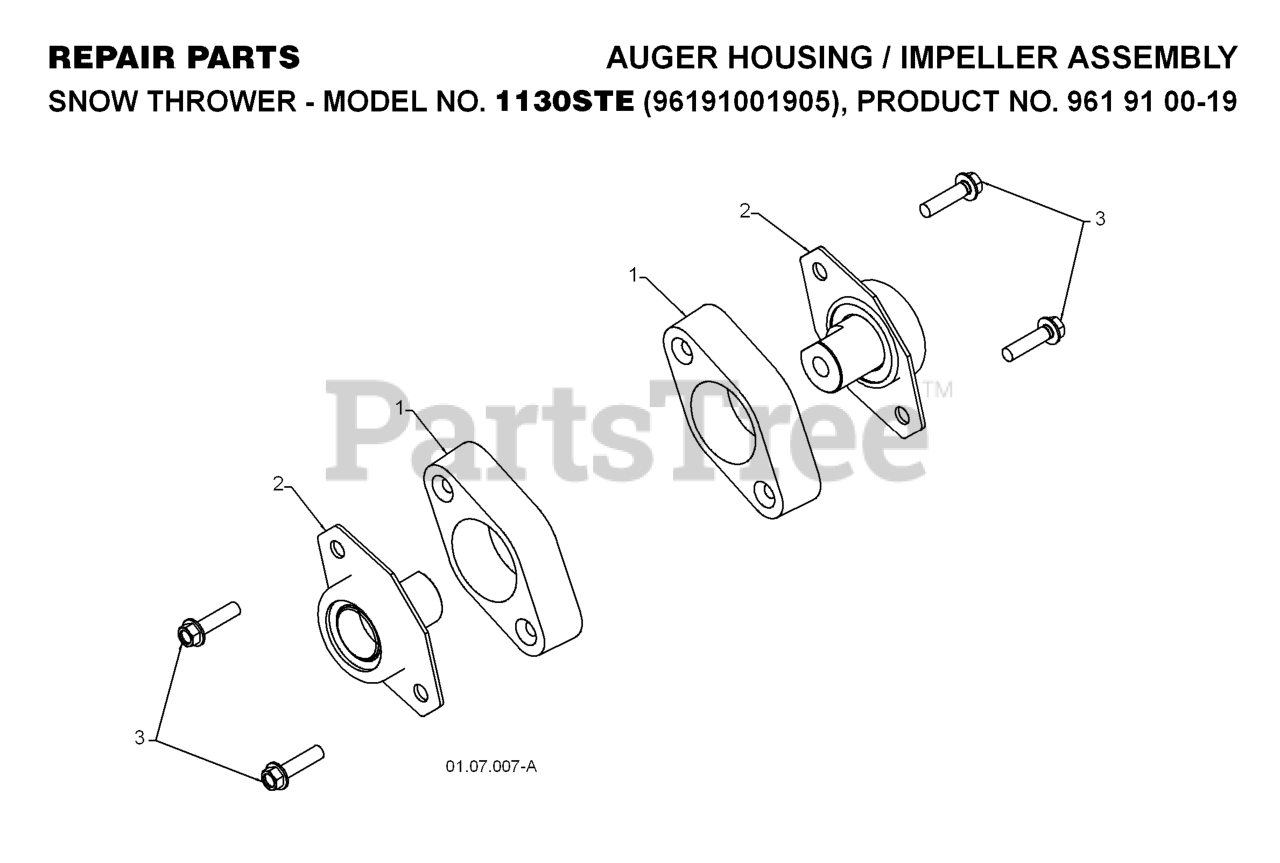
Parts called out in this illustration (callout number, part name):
1	BEARING RETAINER, PLASTIC
2	BEARING.BALL.AUGER
3	SCREW, HEX HD 5/16X1
